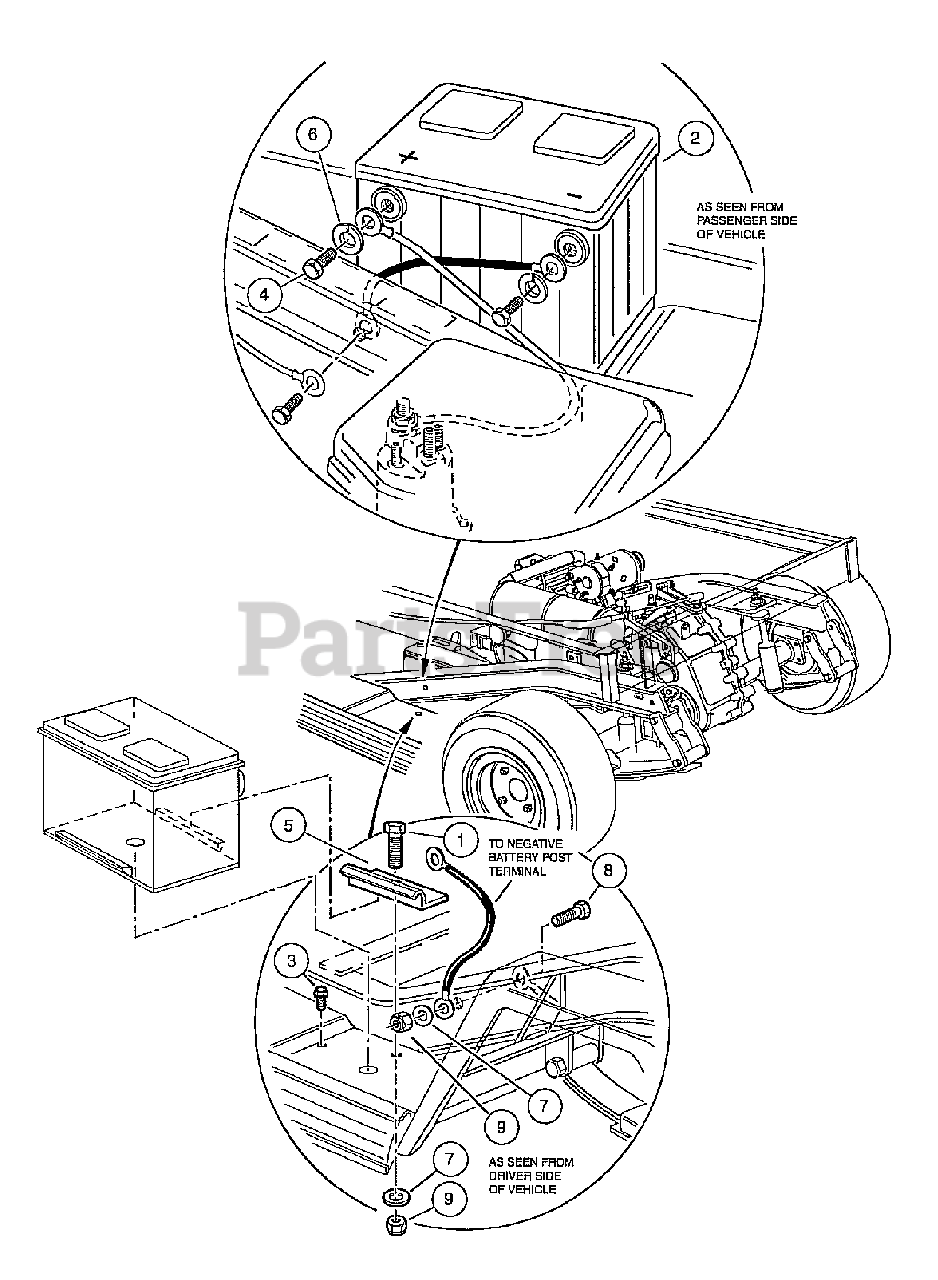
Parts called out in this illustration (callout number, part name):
1	Screw, 5/16-18 X 1.00 Hex Cap
2	Battery, 12-Volt
3	Screw, 5/16-18 X 0.75 Thread-Forming
4	Screw, 3/8-16 X 0.50 Stainless Steel Hex-Head
5	Clamp, Battery
6	Lockwasher, 3/8 Stainless Stl
7	Washer, 5/16 Type A Flat
8	Screw, 5/16-18 X .75 Hx Hd Cap
9	Locknut, 5/16-18 Nylon Insert
